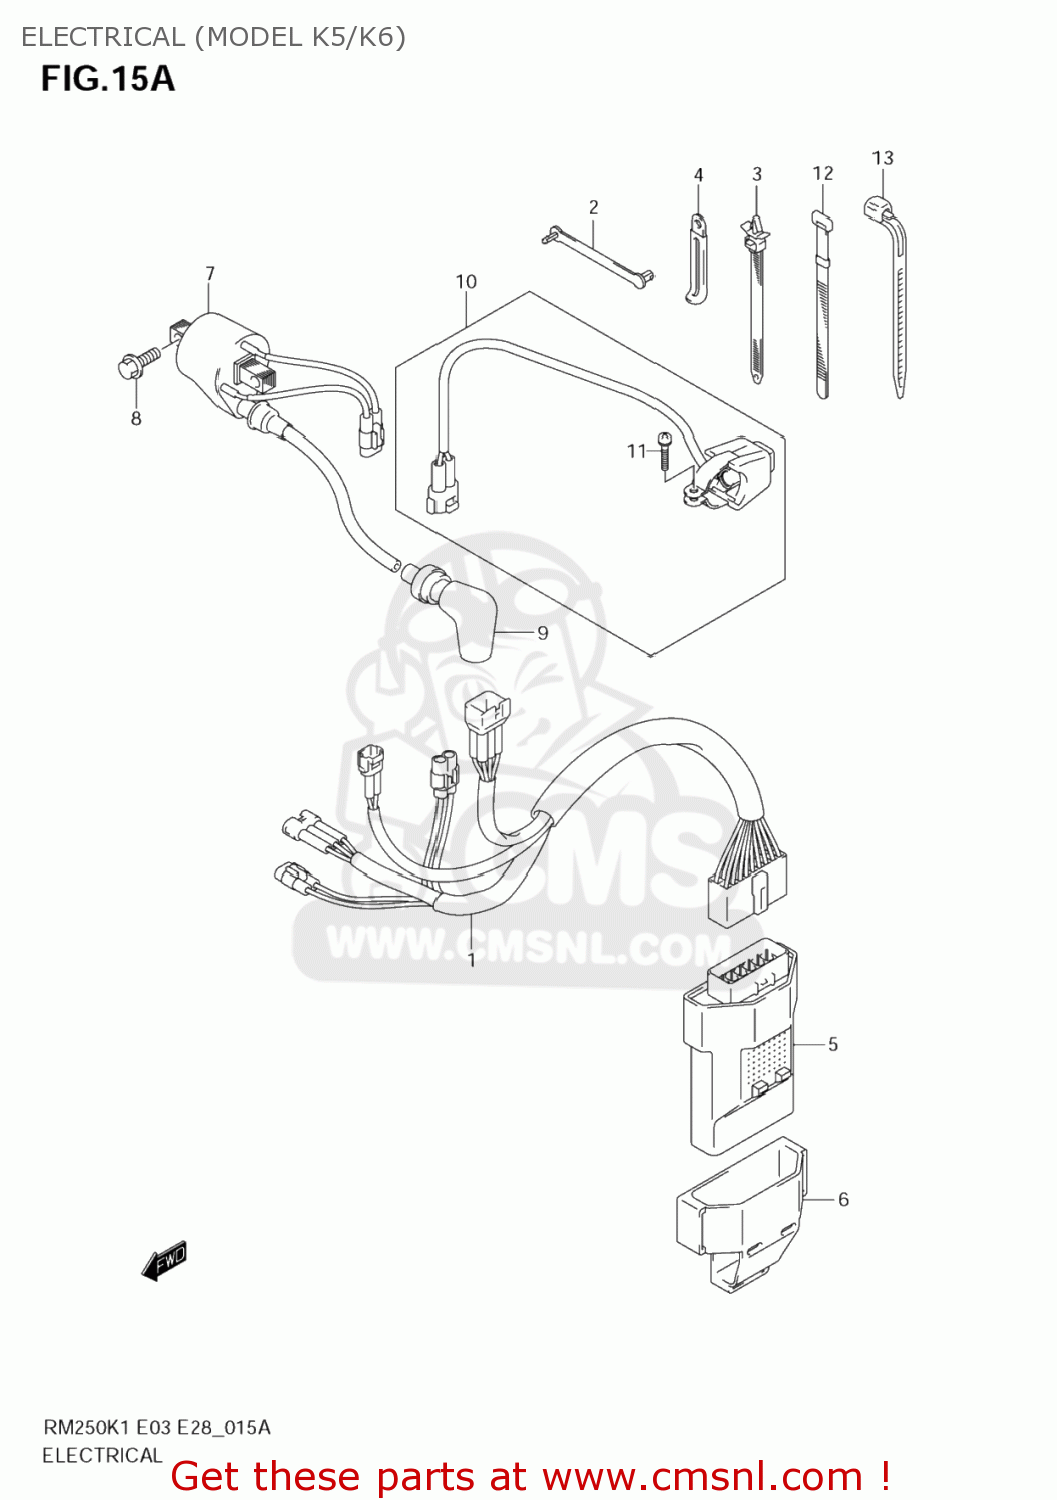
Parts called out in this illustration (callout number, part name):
1	HARNESS,WIRING
2	CLAMP(L:63)
3	CLAMP(L:90)
4	CLAMP(L:45)
5	CDI UNIT
6	CUSHION,CDI UNIT
7	COIL ASSY,IGNITION
8	BOLT(6X16)
9	CAP,SPARK PLUG
10	SWITCH ASSY,ENGINE STOP
11	SCREW
12	CLAMP(L:120)
13	CLAMP(L:95)
